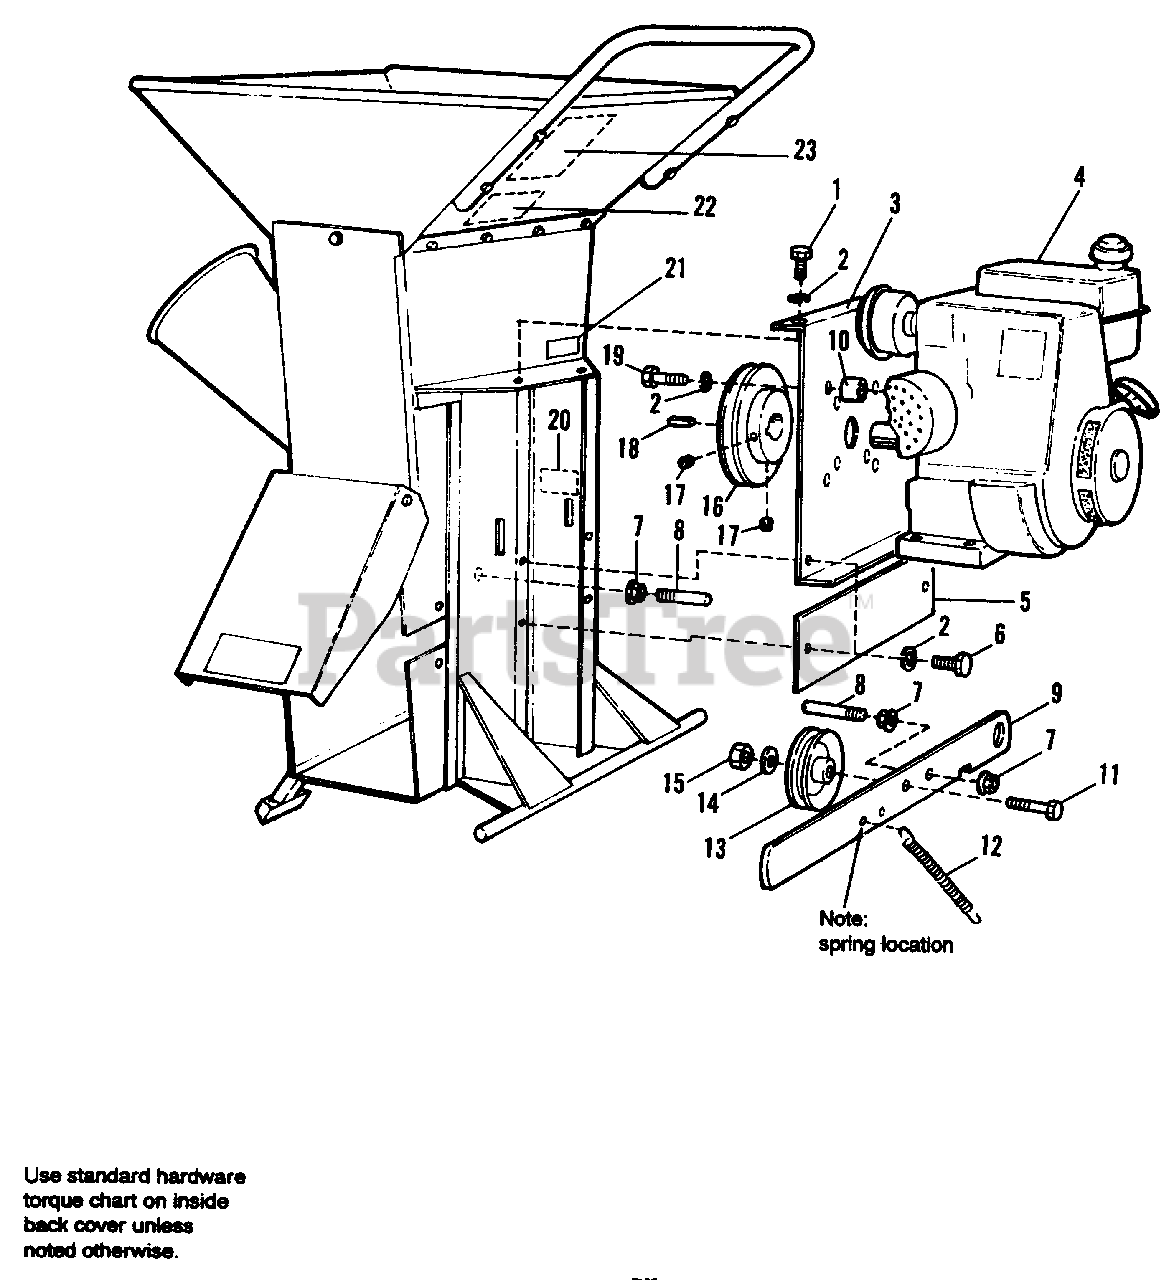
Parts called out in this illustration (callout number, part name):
1	CAPSCREW, Hex, 5/16-18 x 3/4
2	LOCKWASHER, Split, 5/16, (Qty.10-Honda Engine)
3	MOUNT, Engine
5	GUARD, Belt
6	CAPSCREW, Hex, 5/16-18 x 1/2
7	NUT, Hex, Whiz Lock, 1/4-20
8	STUD, 114-20 x 2
10	SPACER (Honda Engine Only)
11	CAPSCREW, Hex, 3/8-16 x 1-1/2
13	PULLEY, Idler
14	LOCKWASHER, 3/8 Int Tooth
15	NUT, Nylock, 3/8 16
16	PULLEY, For 3/4" Shaft (612 Honda Engine Only)
17	SCREW, Set, 5/16-18 x 1/4
18	KEY, Sq., 3/16 x 1-1/4, for 3/4" Shaft (612 Honda Engine Only)
19	CAPSCREW, Hex, 5/16-24 x 3/4
19	CAPSCREW, Hex, 5/16-24 x 1-1/4 (Honda Engine Only)
20	DECAL, Clutch
21	I.D. PLATE
22	DECAL, Danger
23	DECAL, Caution
